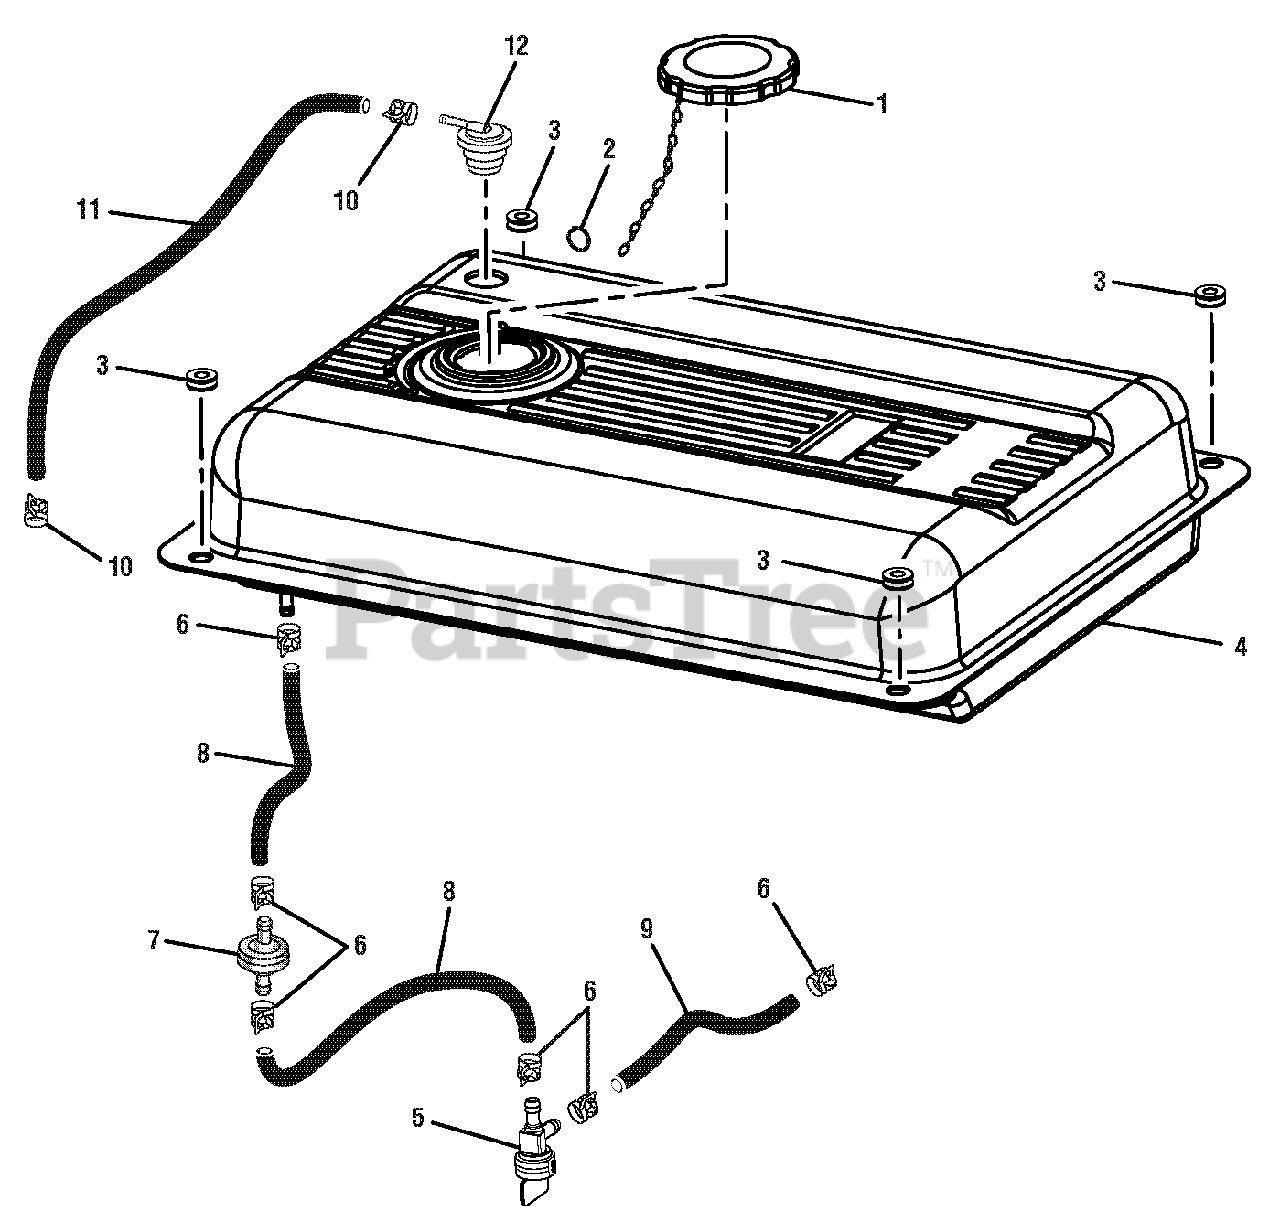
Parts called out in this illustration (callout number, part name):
1	FUEL TANK CAP
2	RING CLIP
3	BUSHING W/INSERT
4	FUEL TANK ASSEMBLY
5	FUEL VALVE
6	FUEL LINE CLAMP (1/2 IN.)
7	FUEL LINE FILTER
8	FUEL LINE (1/4 IN.)
9	FUEL HOSE (1/4 IN.)
10	FUEL LINE CLAMP (7/16 IN.)
11	VAPOR HOSE
12	VAPOR VENT
